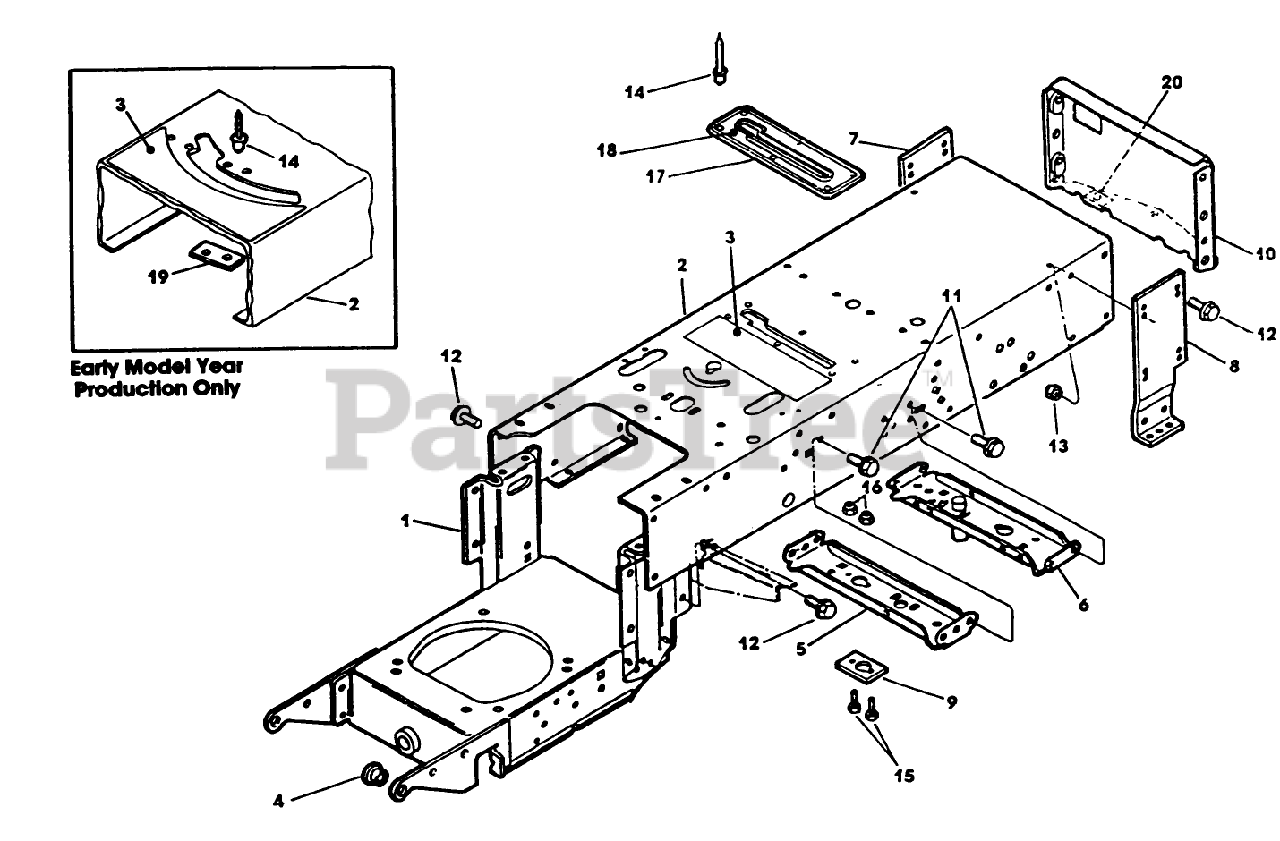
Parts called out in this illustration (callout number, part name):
2	FRAME & DECAL AY (12)
4	BEARING-NYLINER
5	SUPPORT *B
9	BRACKET-SUPPORT *B
10	PLATE AY-HITCH
13	NUT
14	Rivet
15	SCREW
16	NUT-LOCK, CONE
